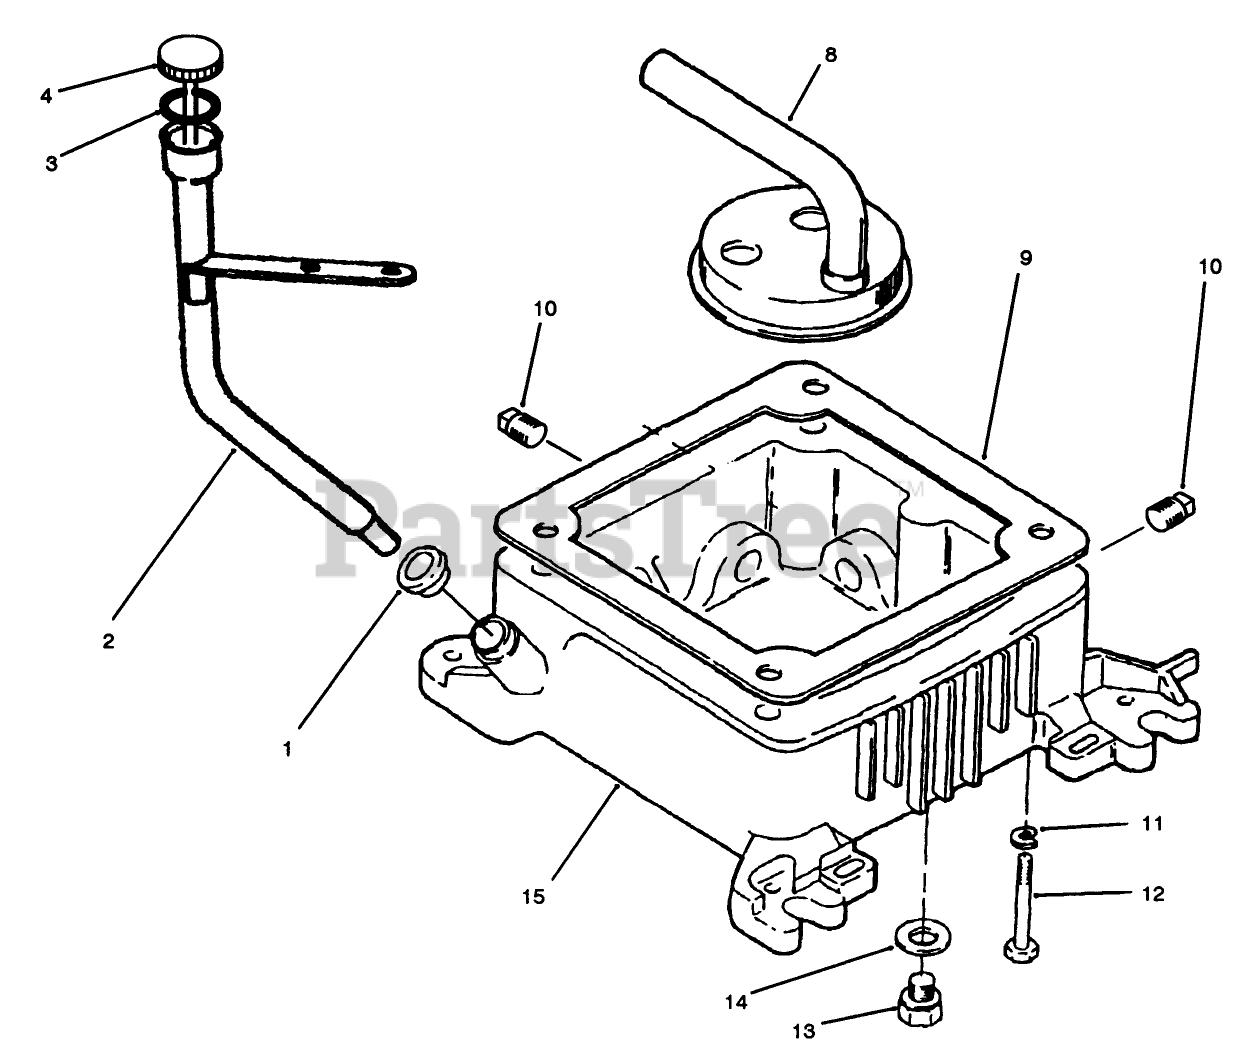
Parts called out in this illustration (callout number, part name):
1	SEAL-OIL FILL TUBE
2	OIL FILL TUBE W/BRKT
3	SEAL 0-RING
4	Cap (Incl. Ref. #3)
8	OIL CUP ASM
9	GASKET
10	PLUG-PIPE, SQH
11	WASHER-LOCK
12	SCREW-HH
13	PLUG-OIL
14	GASKET
15	Base (Incl. Ref. #9, 10, 13 & 14)
